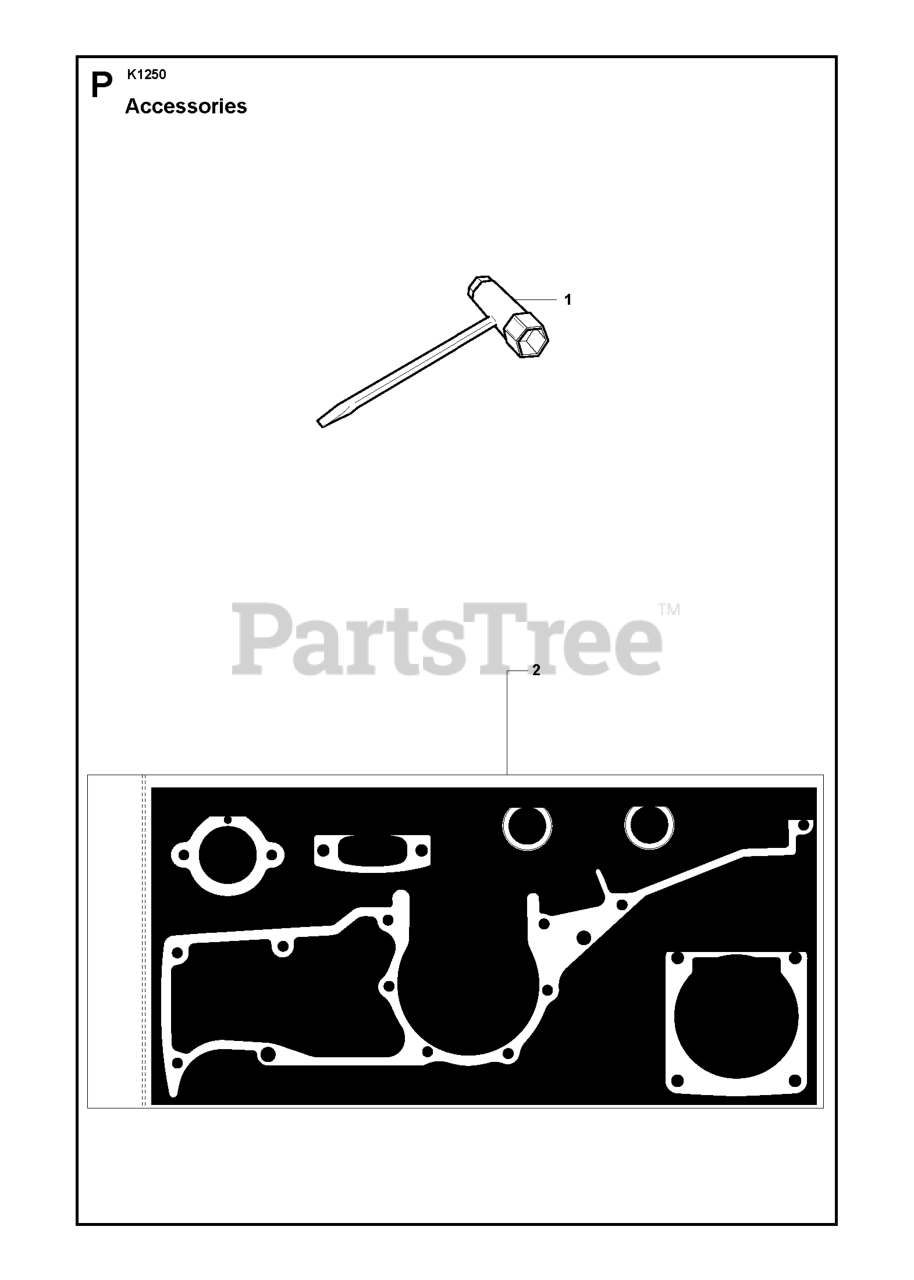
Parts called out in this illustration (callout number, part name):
2	GASKET SET
3	RP GASKET
4	RP GASKET
5	SEALING RING
6	CRANKCASE GASKET
